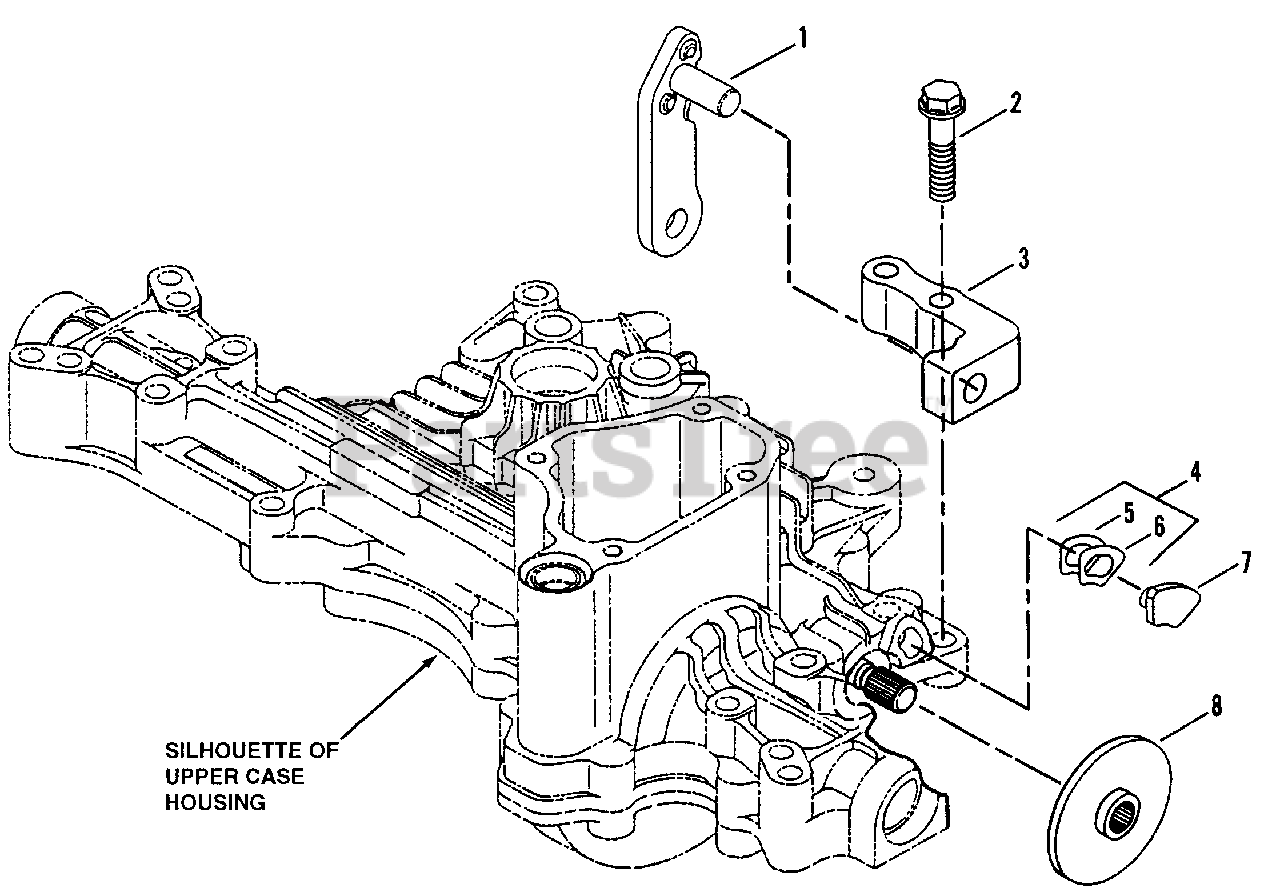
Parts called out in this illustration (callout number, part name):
1	LEVER, Brake
2	CAPSCREW, M10 x 45mm
3	BRACKET, Brake Lever Mounting
4	ASSEMBLY, Shim
7	SHOE, Brake
8	DISK, Brake
